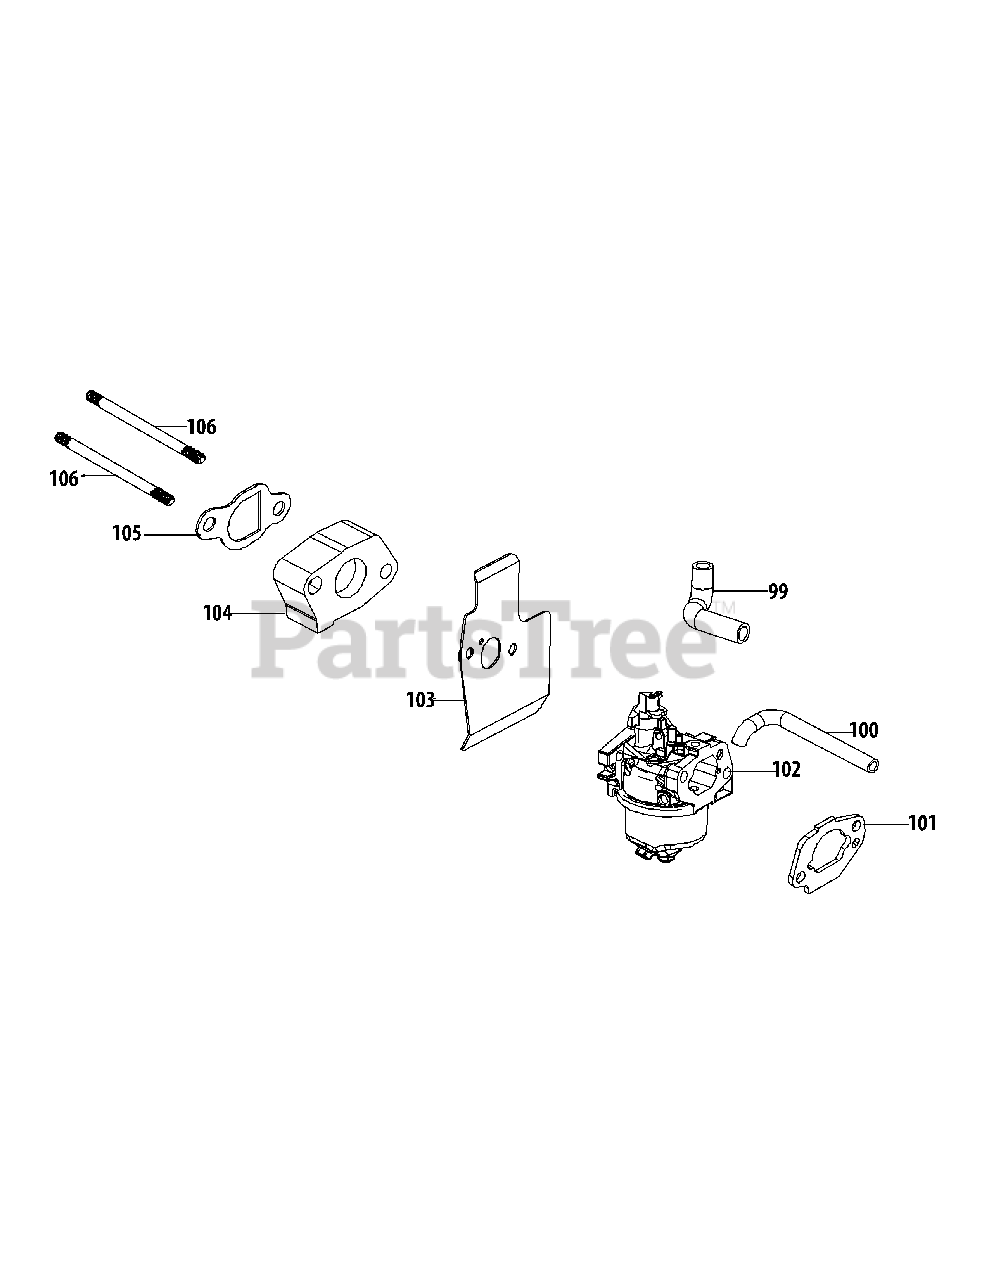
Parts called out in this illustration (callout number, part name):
99	Breather Hose
100	Primer Hose
101	Air Filter Base Gasket
102	Carburetor Assembly
102	Carburetor Rebuild Kit
103	Carburetor Gasket
104	Carburetor Insulator
105	Carburetor Insulator Gasket
106	Carb Stud M6×98
